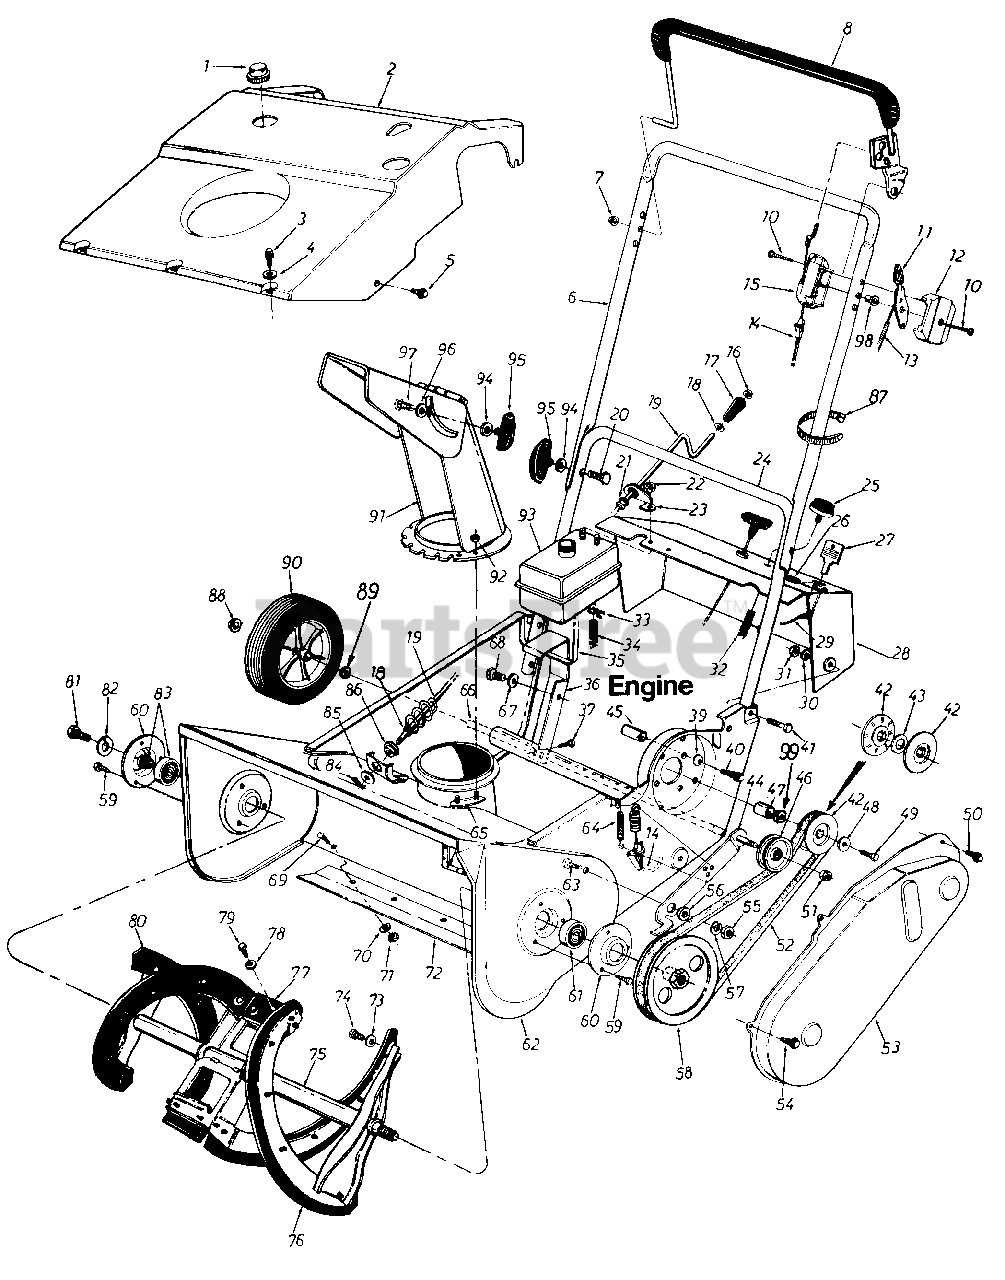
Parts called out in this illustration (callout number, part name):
1	Gas Tank Cap
2	21" Shroud
3	Hex B-Tap Scr. #10 x .38" Lg.
4	Spr.-Wash. .206" I.D. x .448" 0. D.
5	Hex L-Wash. Hd. AB-Tap 1/4 x .62" Lg.
6	Upper Handle Chrome
7	Cap Speed Nut
8	Control Handle Ass'y. L.H.
10	Truss Mach. Hi-B Tap Scr. #12 x 1.5" Lg.
11	Throttle Lever
12	Control Panel Half
13	Throttle Wire 35"
14	Clutch Cable 35" Lg.
15	Clutch Panel Half
16	Push Cap 3/8" Rod
17	Knob 3/8" Dia. Hole
18	Fl-Wash. .385" I.D. x .62" O.D.
19	Chute Crank Ass'y.
20	Curved Carriage Bolt 5/16-18 x 1.75" Lg.
21	Chute Crank Grommet
22	Hex L-Nut 1/4-20 Thd.
23	Upper Chute Crank Brkt.
24	Lower Handle Chrome
25	Primer
26	Plastic Plug 11/4"
27	Plastic Key
28	Dash Panel Ass'y.
29	Ignition Wire
30	L-Wash. 5/16" I.D.
31	Hex Nut 5/16-18 Thd.
32	Primer Hose 11" Lg.
33	Hose Clamp .406" Dia.
34	Gas Line 9" Lg.
35	Cable Tie 17.75" Lg.
36	Engine Support Brkt.
37	Hex L-Wash. Hd. AB-Tap Scr. 1/4 x.62" Lg.
39	Bell-Wash. .345" I.D. x .88" O.D.
40	Hex Bolt 5/16-18 x 1.5" Lg.
41	Hex Bolt 5/16-18 x 1.5" Lg.
42	3/8" "V"-Pulley Half .625" I.D. x 6.0" O.D.
43	Fl-Wash. .635" I.D. x .93" O.D.
44	Idler Brake Brkt. Ass'y.
45	Spacer .325" I.D. x .625" O.D. x .875"
46	Fl-Idler w/Flanges 2.12" O.D.
47	Spacer .635" I.D. x .89" O.D. x .57"
48	Bell-Wash. .345" I.D. x .88" O.D.
49	Hex Bolt 5/16-24 x .75" Lg.
50	Hex L-Wash. Hd. AB-Tap Scr. 1/4 x.62" Lg.
51	Hex Patch L-Nut 3/8-24 Thd.
52	"V"-Belt 1/2" X 35" Lg.
54	Hex B-Tap Scr. 1/4" X .38" Lg.
55	Hex Nut 5/16-18 Thd.
56	Shld Spacer .50" Dia. x .27" Lg.
57	L-Wash. 5/16" I.D.
58	1/2 " "V"-Puiley 1/2-20 L.H. x 6" O.D.
59	Hex B-Tap Scr. 1/4" X .38" Lg.
62	21" Blower Hsg. Ass'y.
63	Truss Mach. Scr. 5/16-18 x .75" Lg.
64	Extension Spring .33" O.D. x 1.12" Lg.
65	Chute Flange Keeper Ass'y.
66	Wheel Axle Tubing
67	L-Wash. 1/4" I.D.
68	Hex Wash. S-Tap Scr. 1/4-20 x.50" Lg.
69	Carriage Bolt 1/4-20 x .62" Lg.
70	Bell-Wash. .265" I.D. x .75" O.D.
71	Hex Nut 1/4-20 Thd.
72	Shave Plate
73	Fl-Wash. .281" I.D. x .50" O.D.
74	Hex Wash. B-Tap Scr. 1/4 X .62"
75	Auger Ass'y. 21"
76	Rubber Spiral L.H.
77	Rubber Paddle
78	Fl-Wash. .218" I.D. x .62" O.D.
79	Hex Wash. B-Tap Scr. #10 x .62" Lg.
80	Rubber Spiral R.H.
81	Hex Wash. TT-Tap Cl-Scr. 1/4-20 x .75" Lg.
82	L-Wash. 1/4" I.D.
83	Kit Bearing and Collar
84	Cotter Pin 3132" Dia. x .75"
85	Fl-Wash. .390" I.D. x 1.50" O.D.
86	Hex Bushing .385" I.D.
87	Cable Tie
88	Push Cap 1/2" Dia.
89	Fl-Wash. .510" I.D. x .75" O.D.
90	Wheel & Tire Ass'y. 6 x 1.5
91	5" Dia. Chute Ass'y.
92	Hex L-Nut 1/4-20 Thd.
93	Fuel Tank Two Qt.
94	Bell-Wash. .345" I.D. x .88" O.D.
95	Knob Handle Ass'y.
96	Fl-Wash. .328" I.D. x .68" O.D.
97	Carriage Bolt 5/16-18 x .62" Lg.
98	Control Disc Pin
99	FL. Wash. .635 I.D. x 1.04 O.D.
